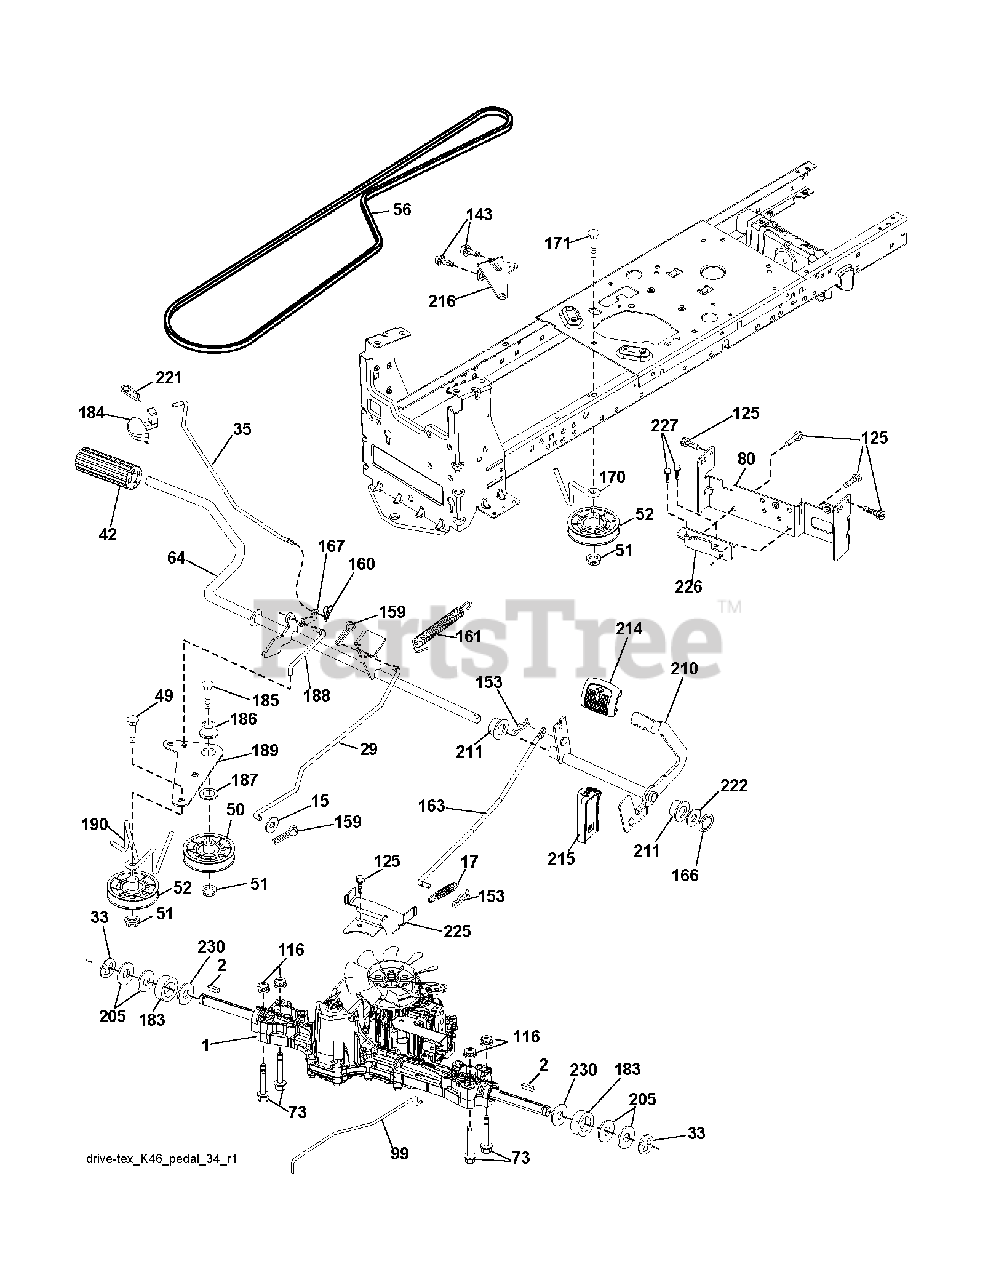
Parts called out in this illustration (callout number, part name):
2	SQUARE KEY
15	WASHER
17	SPRING.BRAKE.K46.GREEN
29	ROD.BRAKE.K46
35	ROD.CNTRL.PARK.PREDATOR.LT.TEX
42	PEDAL COVER T
50	IDLER.FLAT.910.OFFSET
51	NUT LOCK FLG 3/8-16 UNC
52	IDLER.V-GROOVE.910.OFFSET
56	V-BELT.MOWER.92.40.42/K46
64	SHAFT.ASM.PEDAL.BRK.CNTR
80	STRAP TORQUE
99	ROD.SPRING.BYPASS.K46.LT.Z
116	NUT LOCK HEX FLANGE 5/16-18
125	SCREW
143	SCREW LT
153	RETAINER M
159	COTTER PIN
160	RETAINER CLIP
161	SPRING, RETURN LT
163	ROD.CONTROL.PEDAL.K46
166	NUT.PUSH.625
167	LATCH.BRAKE.SPRING
170	KEEPER.V-IDLER.CENTER.
183	SPACER AXLE
184	HANDLE.PARKING.BRK.PRED.LT.RED
186	SPACER.RETAINER
187	WASHER 12/32X2X10GA
188	RP LINK.CLUTCH.GROUND.DRIVE
189	BELLCRANK.GROUND.DRIVE.TEX.
190	KEEPER.BELLCRANK.DRIVE
210	ROCKER.ASM.PEDAL.CONTR
211	BEARING.NYLON
214	PEDAL.FORWARD.PAD.TEX
215	PEDAL.REVERSE.TEX.GT.4
216	BRACKET.PULLEY.IDLER.W/TEX
221	RETAINER.SPRING.CLIP.H
222	WASHER 21/32 X 1-1/4 X 10 GA.
225	KEEPER.BELT.TRANSAXLE.K46
226	BRACKET.MOUNT.TORQUE.K46.TLT
227	SCREW
230	WASHER.HARDENED
